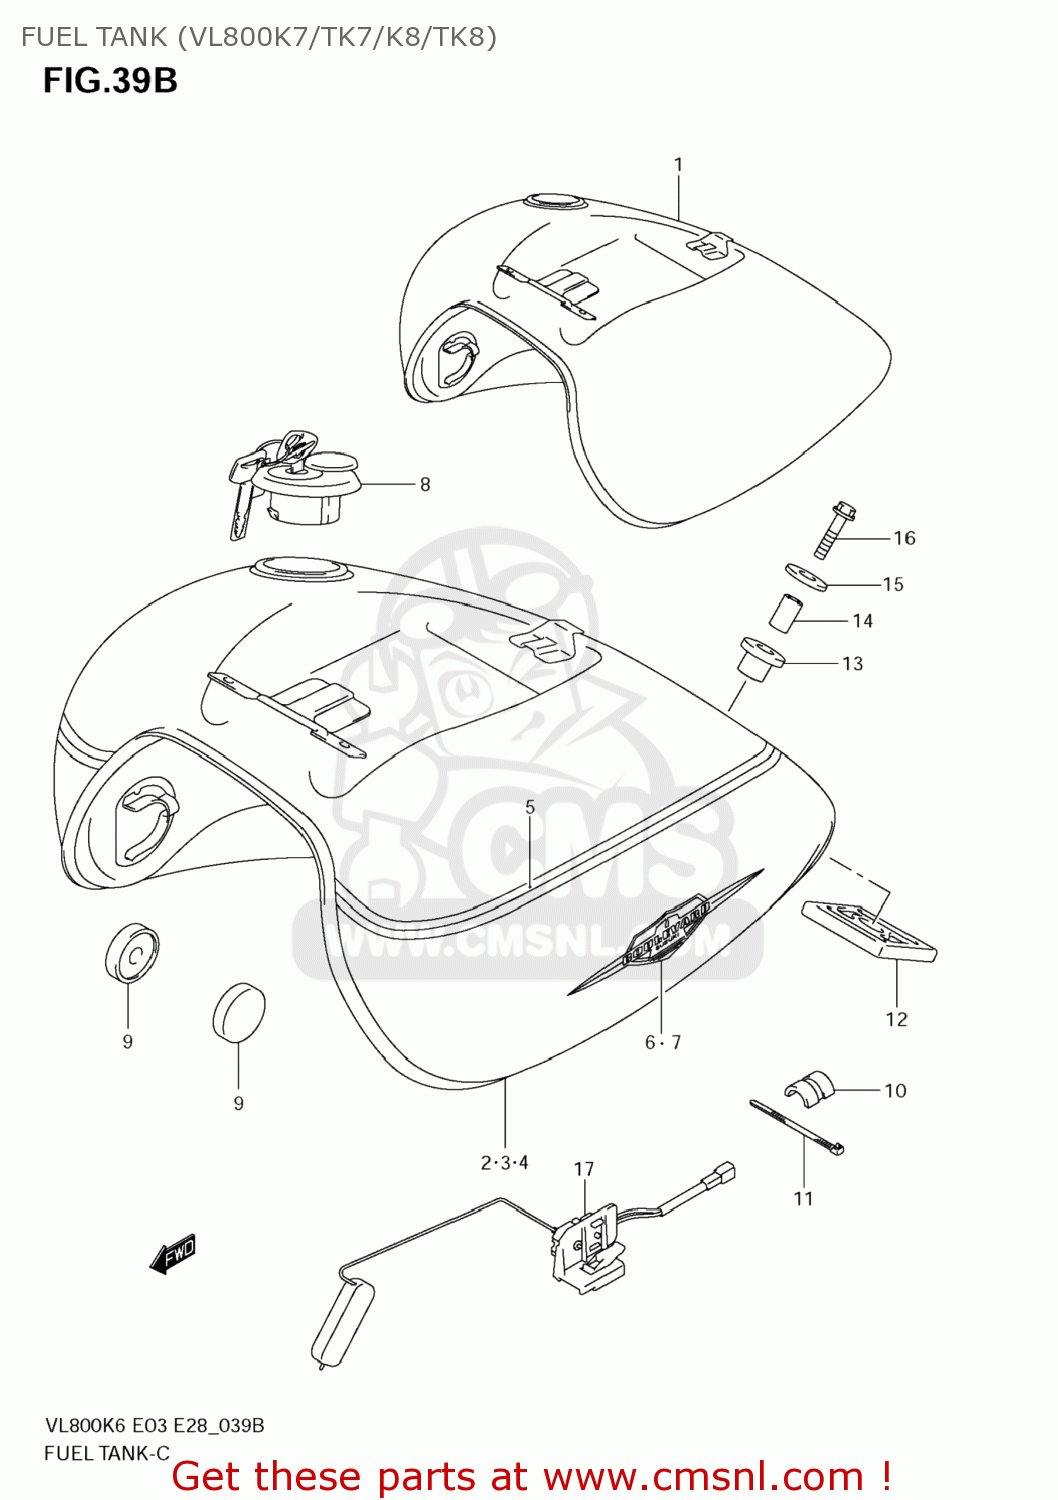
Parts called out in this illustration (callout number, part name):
1	TANK ASSY,FUEL(BLACK)
2	TANK ASSY,FUEL(RED)
3	TANK ASSY,FUEL(GRAY)
4	TANK ASSY,FUEL
5	TAPE SET,FUEL TANK
6	EMBLEM, RH
7	EMBLEM, LH
8	CAP SET,FUEL TANK
9	CUSHION
10	CUSHION,FUEL TANK LWR
11	CLAMP(L:250)
12	CUSHION,FUEL TANK RR LWR
13	CUSHION,FUEL TANK RR UPR
14	SPACER (8.2X12.5X23.5)
15	WASHER (8.5X33X1.6)
16	BOLT
17	GAUGE ASSY,FUE
